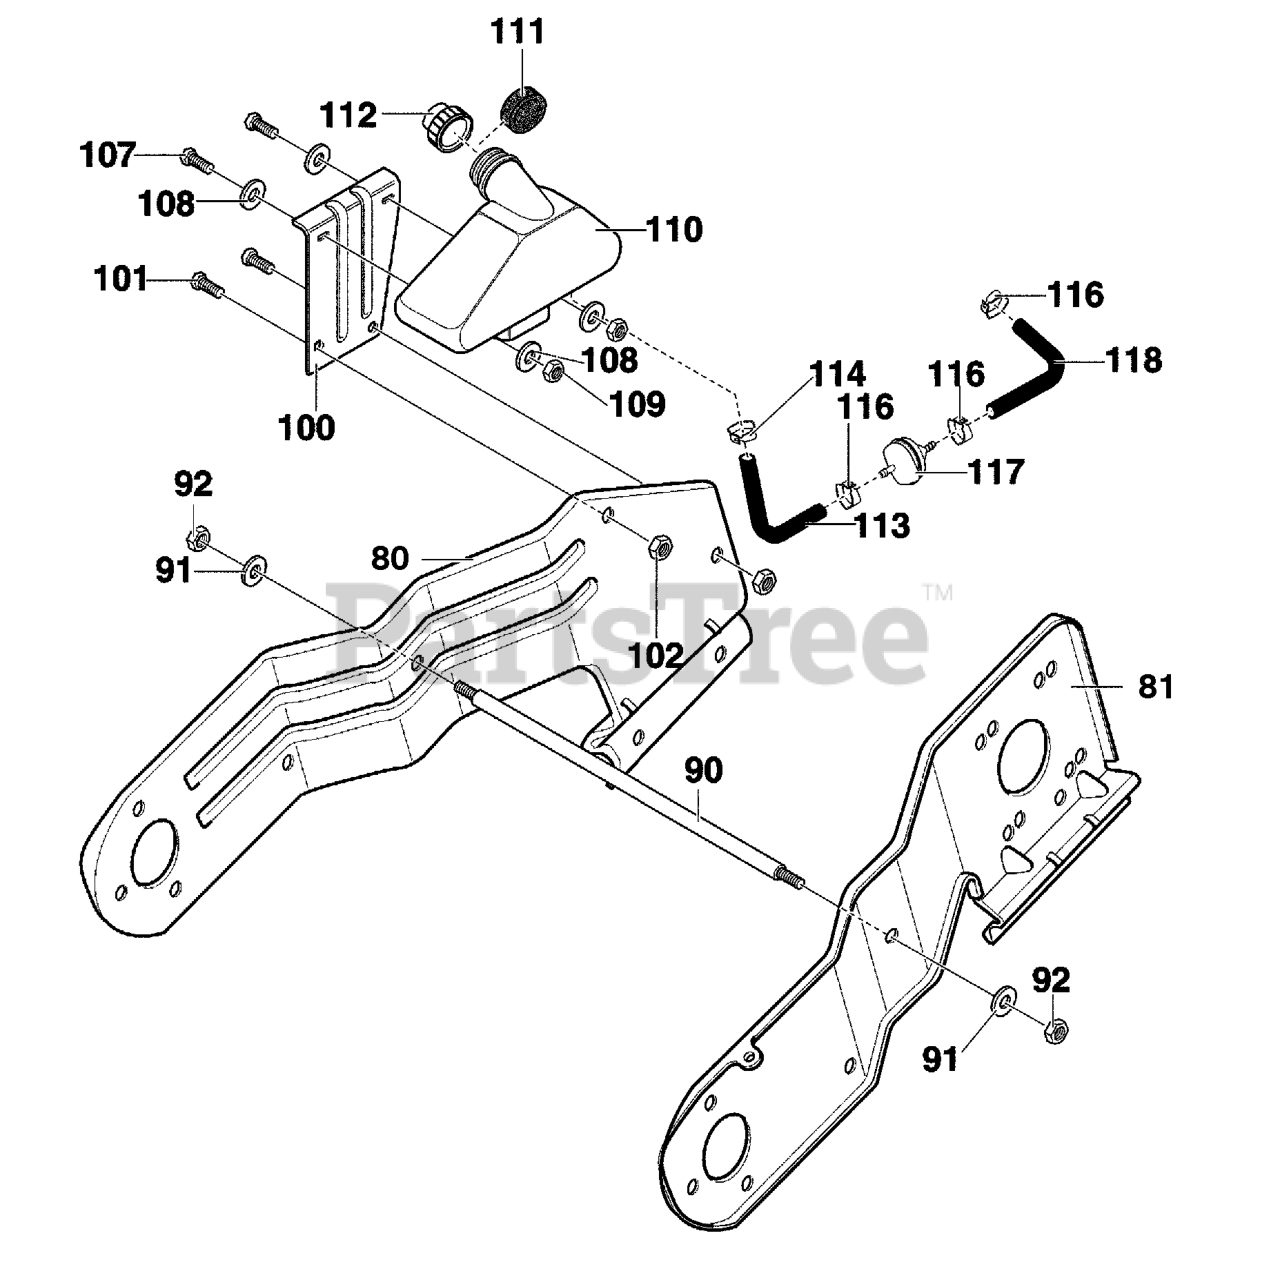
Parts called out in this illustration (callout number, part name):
80	FRAME, SIDE SUPT STEEL RH
81	FRAME, SIDE SUPT STEEL LH
90	ROD, SUPPORT
91	WASHER, HVSPTLK
92	NUT, 3/8-16 REGHEX
100	BRACKET, GAS TANK
101	SCREW, 1/4-20X.75
102	NUT, 1/4-20 REGHEXCTRLK
107	SCREW, 1/4-20X.75
108	WASHER, FLAT
109	NUT, 1/420 REGHEXCTRLK
110	TANK, FUEL
111	RING, FOAM FUEL TANK
112	CAP, GAS
113	TUBING 8 IN.
114	CLAMP, HOSE SCREW
116	CLAMP, HOSE
117	FILTER IN LINE
118	TUBING, 6 IN.
